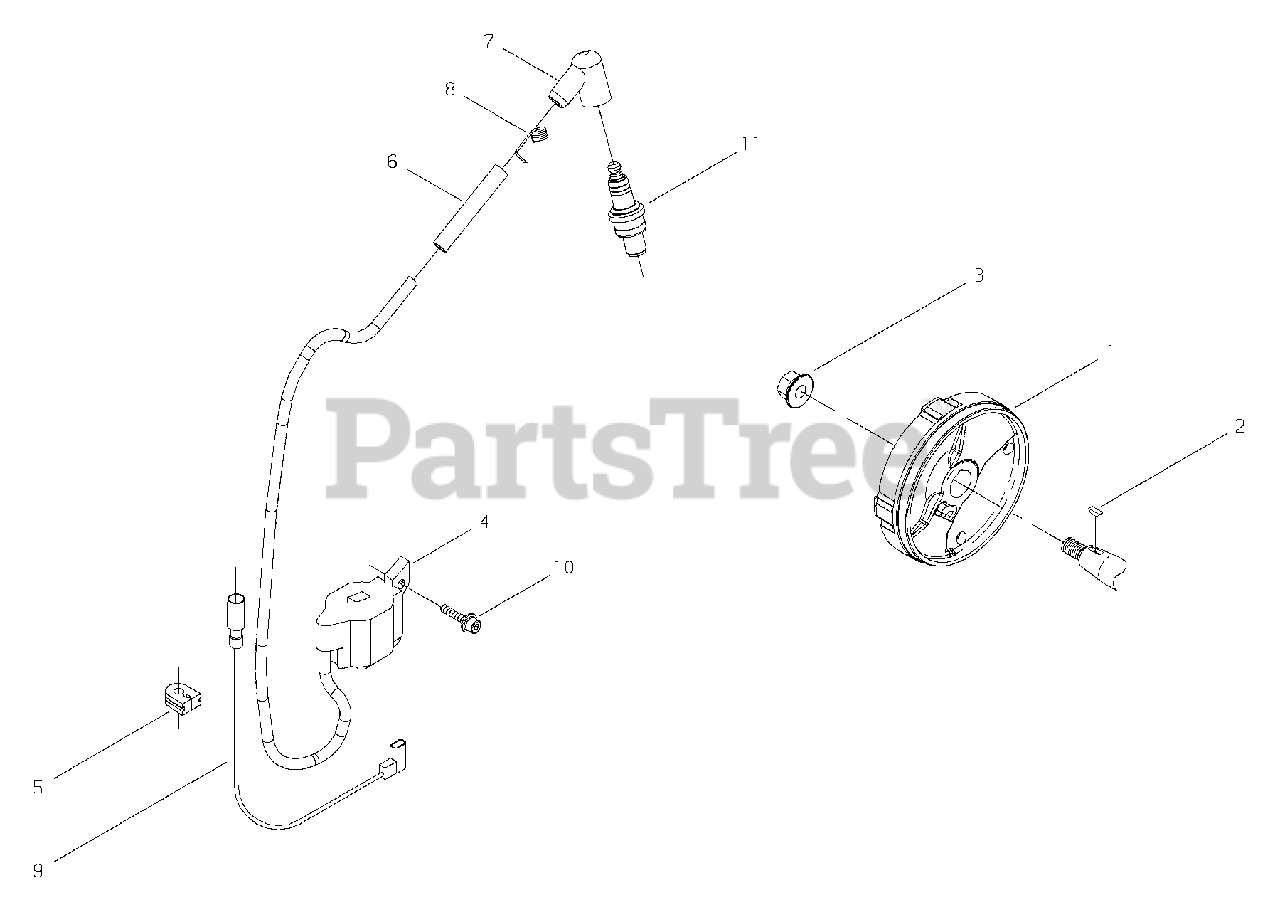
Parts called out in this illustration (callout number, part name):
1	FLYWHEEL
2	KEY - 3X10
3	NUT - 8
4	IGNITION COIL ASSY
6	TUBE
7	CAP, SPARK PLUG
8	TERMINAL, SPARK PLUG CAP
9	LEAD - IGNITION
10	SCREW - 4X20
11	SPARK PLUG -- CMR-5H
